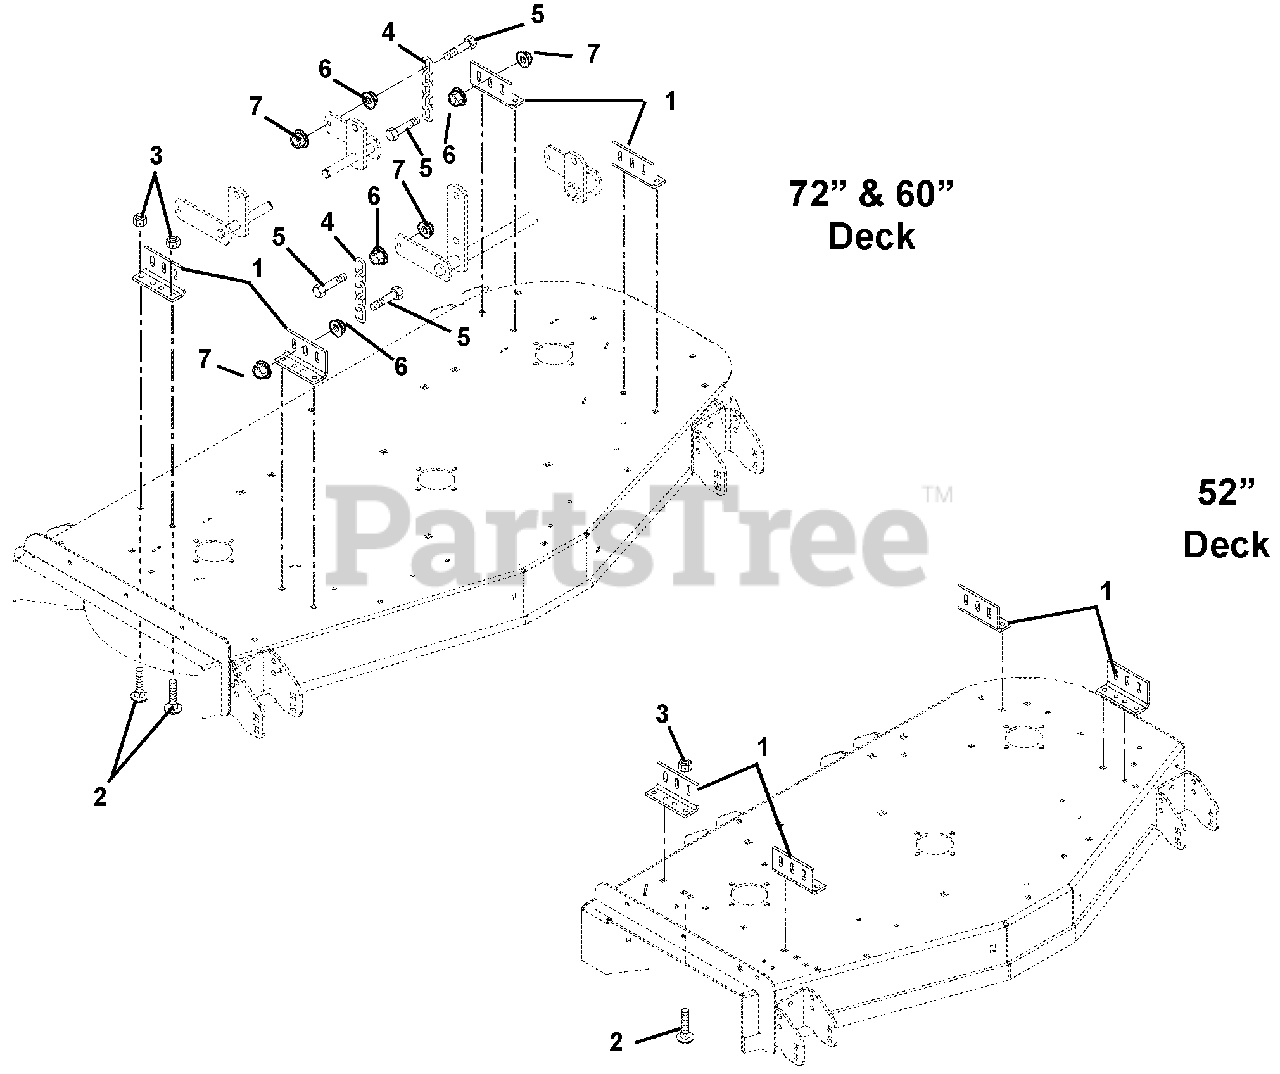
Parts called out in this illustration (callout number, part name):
1	Bracket, Mower Mounting
2	Bolt-Round Head Square Neck .38-16 x 1.00 Grade 2
3	Nut-Locking-Top-Flange .38-16
4	Chain, Link
5	Bolt-Hex M12-1.75 x 55 Grade 5
6	Nut, Spin Lock Flange M12-1.75
7	Nut-Locking-Top-Flange M12-1.75
